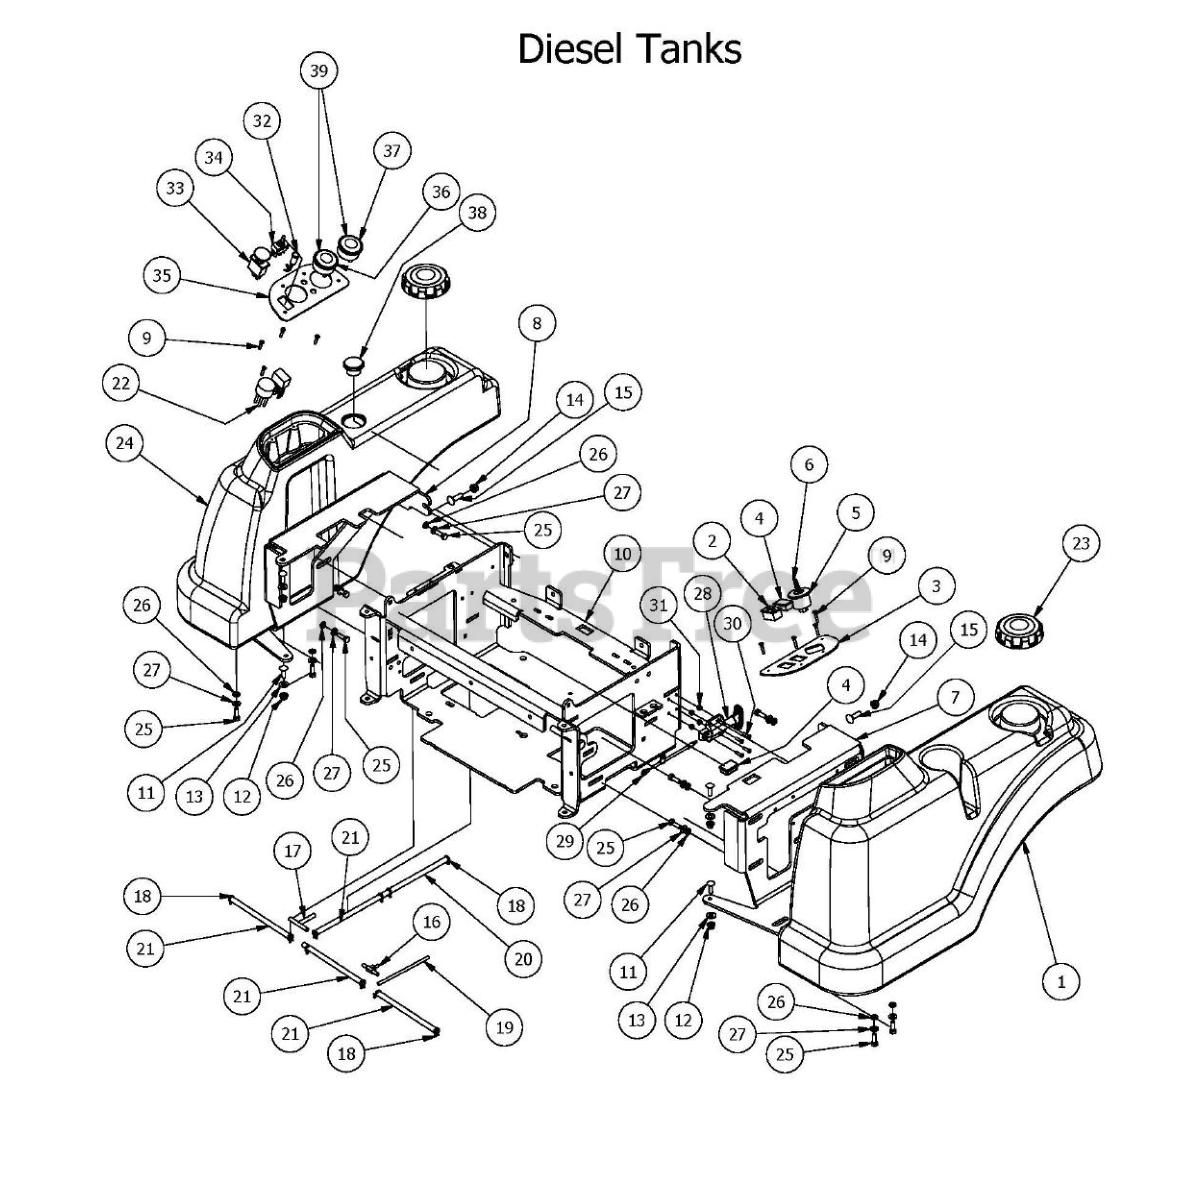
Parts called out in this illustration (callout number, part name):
1	Left Fuel Tank with Fender
2	Hour Meter
3	Control Panel (Left)
4	Light Plug
5	Ignition Switch
6	Ignition Key
7	Left Tank Support
8	Right Tank Support
9	10-32 x 1 Button Head Bolt
10	Diesel Seat Frame
11	5/16" x 1" Carriage Bolt
12	5/16" Flange Nut
13	.360 ID Plastic Washer
14	3/8" Nylock Flange Nut
15	3/8" x 1 1/4" Carriage Bolt
16	Brass fuel line T
17	fuel line T
18	1/4 Fuel Hose Clamp
19	3/16 Fuel Line
20	5/16" fuel line hose
21	1/4" Fuel Line Hose
22	Wiring Harness -35 & 28 Diesel
23	Diesel Fuel Cap - 3.5" Neck
24	Right Fuel Tank with Fender
25	5/16" x 1" Bolt
26	5/16" Lock Washer
27	5/16" Flat Washer
28	2016 T Handle Release
29	2015 Seat Latch Cable
30	10-24 x 1 BS C/S 18-8 SS
31	10-24 Nylon Insert Locknut Zinc Orange Nylon
33	PTO Engager
34	Deck Lift Joystick
35	Diesel Control Panel Right 2012
36	2" Water Temperature Gauge
37	2" Oil Pressure Gauge
38	Fuel Gauge and Grommet
39	Pigtail-2" Faria Gauge -2012 & up (Used For the water and Oil Gauges)
